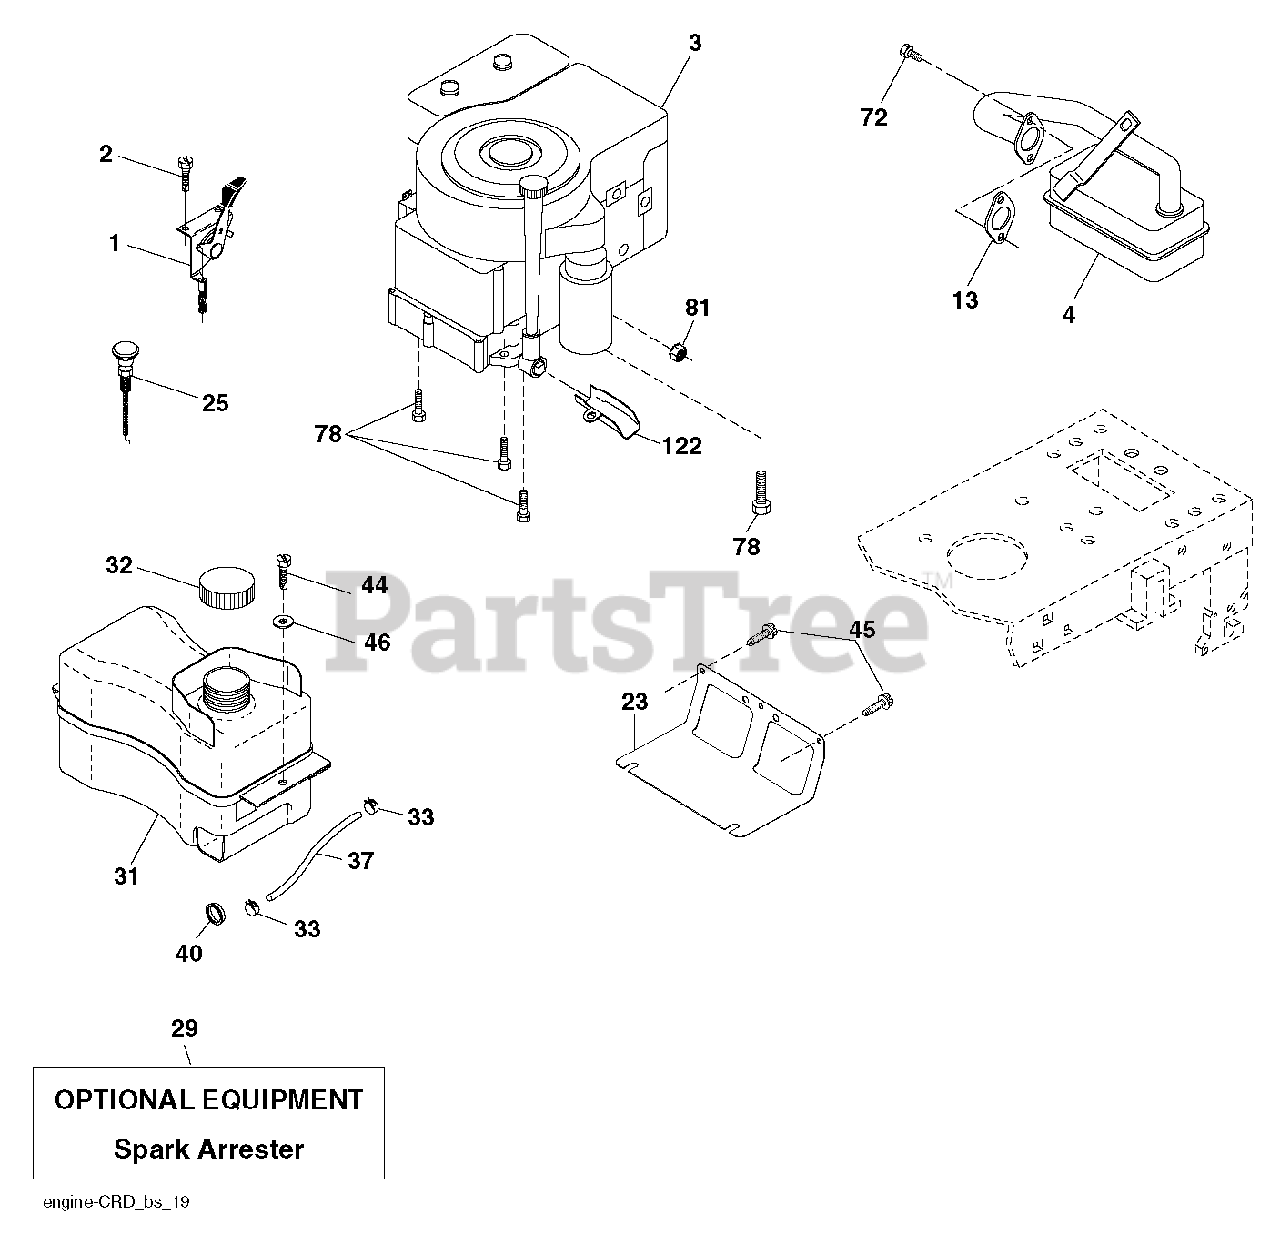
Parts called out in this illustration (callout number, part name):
1	CONTROL TH/CH FLAG
2	SCREW
13	REPL BY 532 27 22-93
23	SHEILD.BROWNING.DBR.GUARD
25	KNOB.ERGO.EXTENDED.RED (1 2)
29	ARRESTER SPARK (OPTIONAL)
32	CAP ASM.FUEL.2.25"FR.
44	SCREW HEXWSHR 1/4-20X3/4
45	SCREW, 3/8-16X3/4
72	SCREW.SOCKET HD.5/16-1
81	NUT
122	EXTENSION DRAIN OIL
